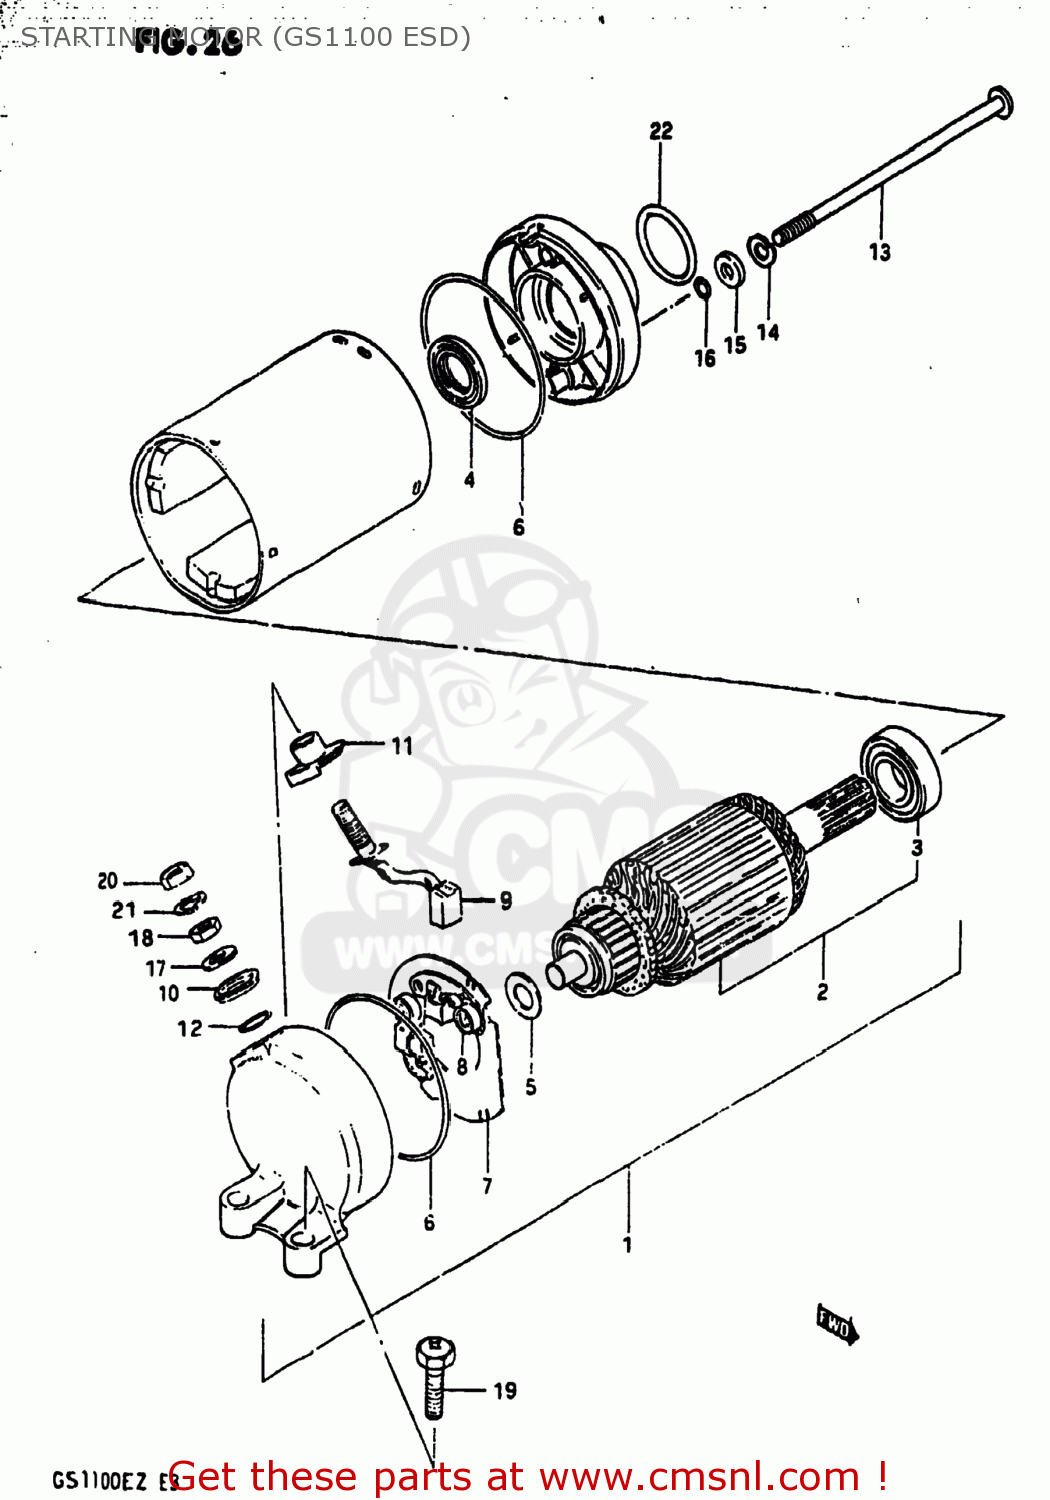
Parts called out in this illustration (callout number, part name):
1	MOTOR ASSEMBLY,STARTING
2	ARMATURE
3	BEARING
4	SEAL,OIL
5	SHIM,ARMATURE
6	O RING
7	HOLDER,BRUSH
8	SPRING
9	BRUSH SUB ASSY,STARTING MOTOR
10	BUSHING
11	BUSH,B
12	O RING
13	BOLT
14	LOCK WASHER
15	WASHER
16	O RING
17	WASHER
18	NUT 6MM
19	SCREW (6X25)
20	NUT 6MM
21	LOCK WASHER
22	O RING(D:3,ID:24.5)
